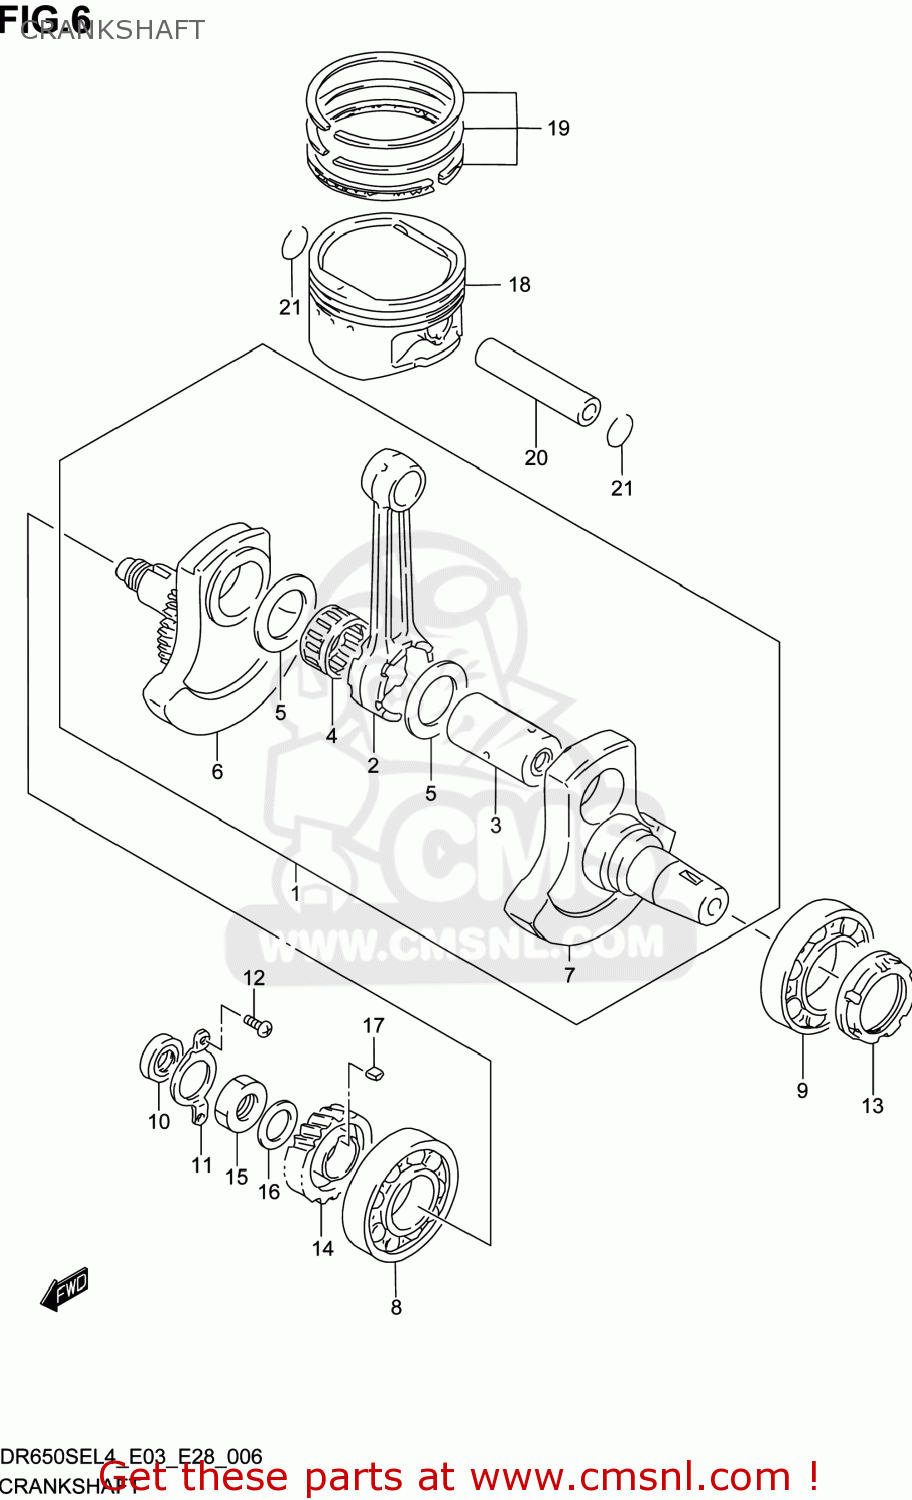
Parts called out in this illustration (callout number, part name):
1	CRANKSHAFT SET
2	CONNECTING ROD
3	PIN,CRANK
4	BEARING(37X47X25)
5	WASHER(37X55X1)
6	CRANKSHAFT SET,R
7	CRANKSHAFT,L
8	BEARING(40X80X18)
9	BEARING(45X85X19)
10	SEAL,OIL(16X30X6)
11	RETAINER,CRANKSHAFT BEARING,R
12	SCREW
13	NUT,CRANKSHAFT BRG,L
14	GEAR,PRIMARY DRIVE(NT:28)
15	NUT
16	WASHER
17	KEY
18	PISTON (100.00MM)
19	RING SET,PISTON
20	PIN,PISTON
21	CIRCLIP
